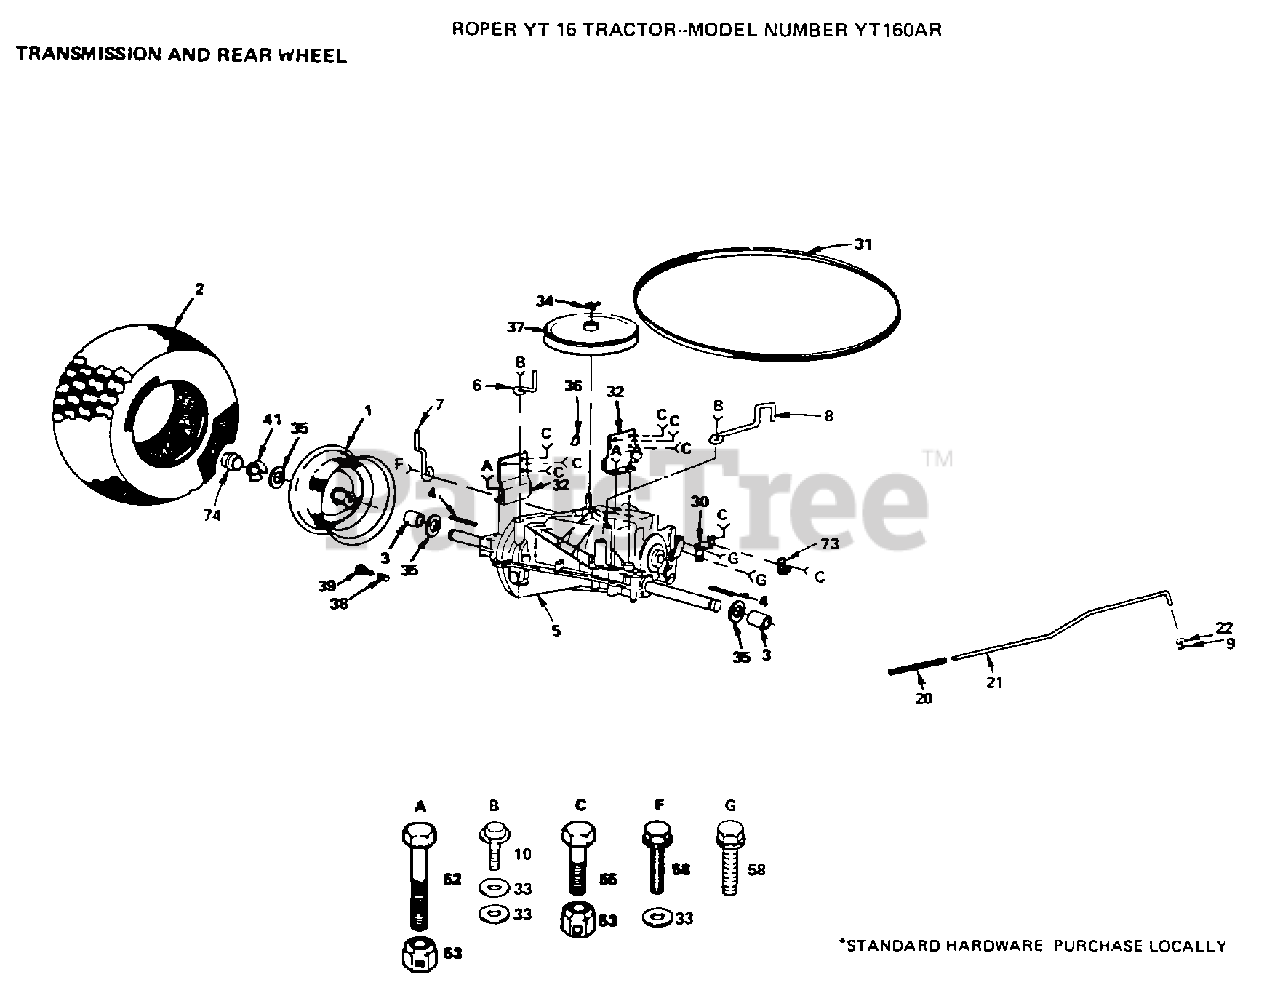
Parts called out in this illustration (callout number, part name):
3	WHEEL SPACER LT
6	BELT SNUBBER T
8	RETAINER, BELT
9	COTTER PIN
10	SCREW TI
22	WASHER
30	STRAP - TORQUE
33	WASHER M
34	KLIP RING
37	PULLEY-INPUT LT
38	VALVE CAP
39	VALVE STEM LT
41	E-RING LT
52	BOLT
58	SCREW
73	INSUL CLIP T
